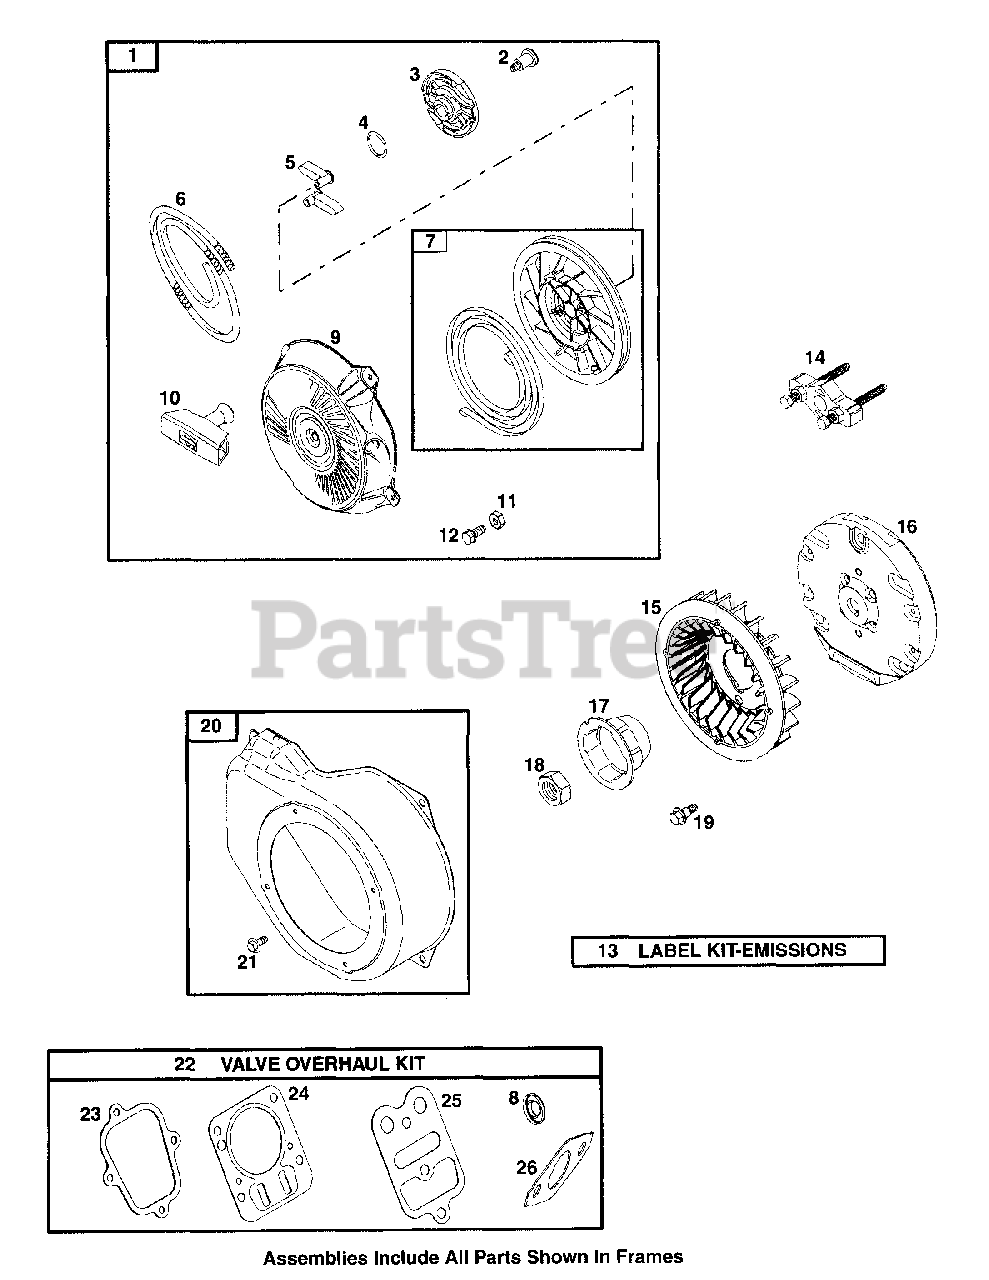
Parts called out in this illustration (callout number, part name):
1	Starter-Rewind
2	Screw (Pawl Friction Plate)
3	Plate-Pawl Friction
4	Spring-Friction
5	Pawl-Ratchet
6	Rope-Starter
7	Pulley/Spring Assembly
8	Seal-Valve
9	Rewind Starter Housing
10	Starter Rope Grip
11	Nut (Rewind Starter)
12	Screw (Rewind Starter)
13	Emissions Label
14	Flywheel Puller
15	Fan-Flywheel
17	Cup-Flywheel
18	Nut (Flywheel)
19	Screw (Flywheel)
20	Housing-Blower
21	Screw (Blower Housing)
22	Kit-Valve Overhaul
23	Gasket-Rocker Cover
24	Cylinder Head Gasket
25	Cylinder Head Plate Gasket
26	Gasket-Intake
